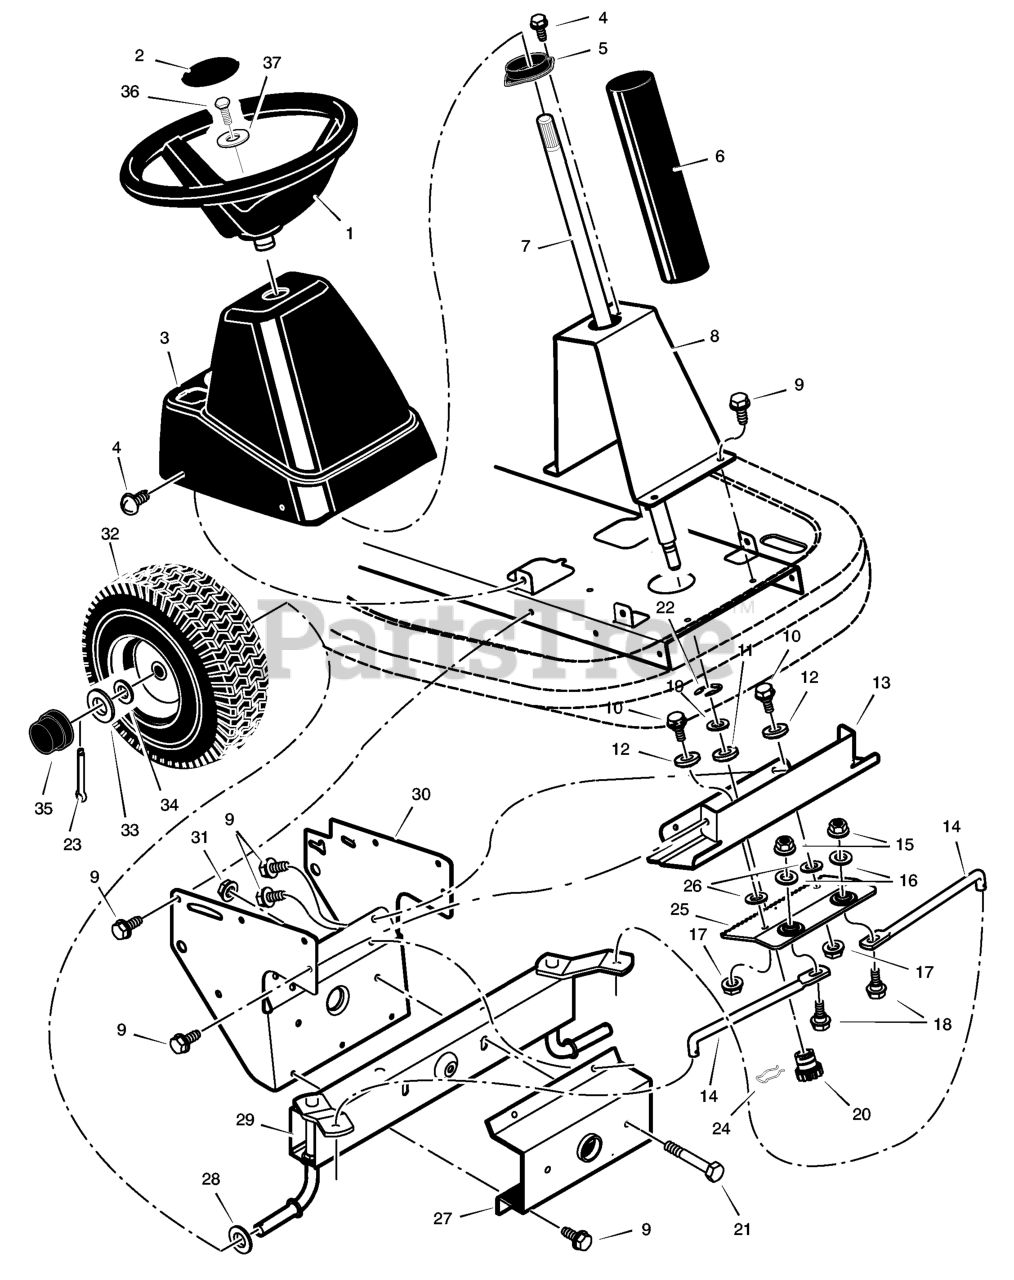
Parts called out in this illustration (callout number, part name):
1	Wheel, Steering
2	Insert, Steering
3	Console, Low -Black
4	Screw
5	Bearing, Upper Steering
6	Tube, Steering
7	Shaft, Steering
8	Support, Steering
10	Bolt, Shoulder
11	Bearing, Lower Steering
13	Plate, Gear Mounting
14	Link, Drag
15	Nut, Flange
16	Washer
17	Nut, Flange
18	Bolt, Hex
19	WASHER, 1-1.3 16G FLT
20	Gear, Pinion
21	Bolt, Hex
22	E-Ring, Retainer
23	Pin, Cotter
24	Retainer, Spring
25	Rack, Steering
26	Washer
27	Bracket, Axle Front
28	Washer
29	Axle & Spindle Assembly
30	Bracket, Support
31	Nut, Flange
32	Wheel, Front
34	Washer
35	Cap, Hub
36	Screw, Hex
37	Washer
